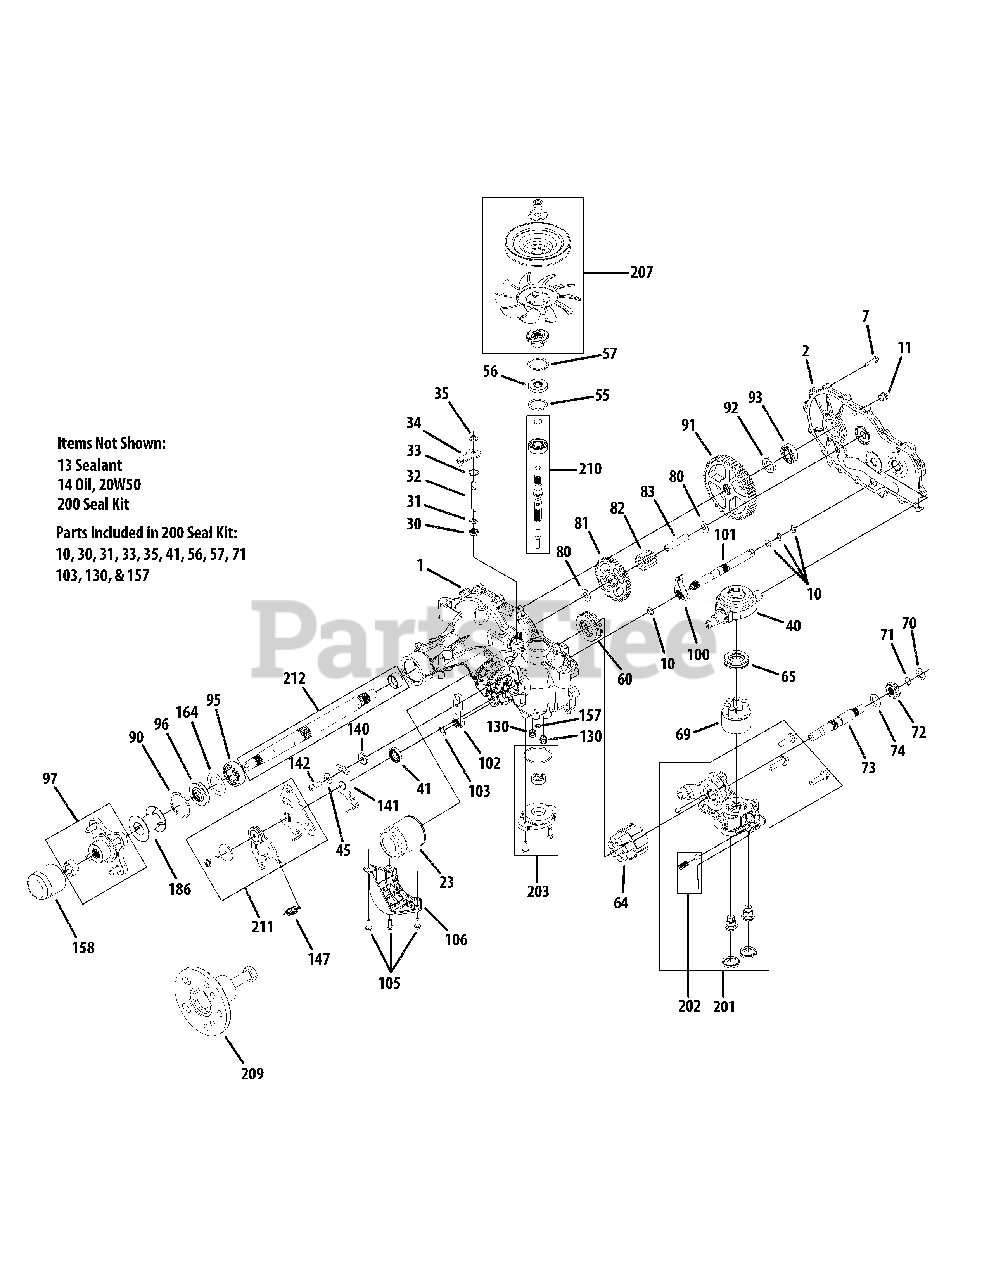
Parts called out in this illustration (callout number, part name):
1	Kit, Main Housing, RH Charge
2	Kit, Side Cover RH
7	Screw, Hex Washer
23	Filter, Spin-On 2.6 x 3.0
30	Seal, Lip, .375 x .75 x .25
31	Ring, Retaining .375 External
32	Rod, Bypass
33	Ring Retaining .750 Internal
34	Arm, Bypass
35	Ring, Ret .375 External
40	Trunnion, Swashplate
41	Seal, Lip 18 x 32 x 7
45	Washer, .34 x .88 x .06
55	Washer, 1.23 x 1.57 x .04
56	Seal, Lip 17 x 40 x 7
57	Ring Retaining Internal
60	Bearing, Thrust 35 x 62 x 18
64	Kit, 16cc Cylinder Block Assembly
65	Thrust Bearing, 30 x 52 x 13
69	Kit, Block, 7 Piston
70	Washer, .63 x 1.00 x .05
71	Ring, Reatining, Motor Shaft
72	Gear, 14T (Steel)
73	Shaft, Motor
74	Washer, .71 x 1.16 x .04
81	Gear, 45T
82	Gear, 11T (Steel)
83	Pin, Jackshaft
90	Ring, Retaining 2.25 Internal
91	Gear, 54T
92	Spacer, .750 x 1.00 x .257
93	Bearing, Ball 3/4 x 40mm x 12mm
95	Bearing, Ball 25.4 x 52 x 15
96	Seal, Lip, 1.0 x 2.06 x .38
97	Kit, Hub 4-Bolt
100	Pawl, Brake
101	Kit, brake Shaft
102	Handle, Actuating
103	Ring, Retaining, External .438
105	Screw, Hex Washer 1/4-20 x .75
106	Guard, Filter, RH
111	Kit, Fitting 1/2 Beaded 9/16 SAE
130	Tube, Charge Triple O-Ring
140	Spacer, .320 x 1.005 x .150
141	Arm, Neutral Right
142	SHCS, 5/16-24 x 7/8 (W/Patch)
147	Spring, Extension
157	Seal, Gerotor .281 x .420 x .160
158	Cap, Axle
164	Spacer, 1.355 x 2.035 x .021
186	Tube, Axle 2.03
200	Kit. Seal, ZT-2800
201	Kit, Center Section RH Charge
202	Kit, Charge Relief
203	Kit, Charge
207	Kit, Fan Pulley
207	Fan Only
207	Pulley Hub
209	Kit, Hub Puller
210	Kit, Input Shaft
211	Kit, RTN Bidirectional
212	Kit, Shaft Axle
